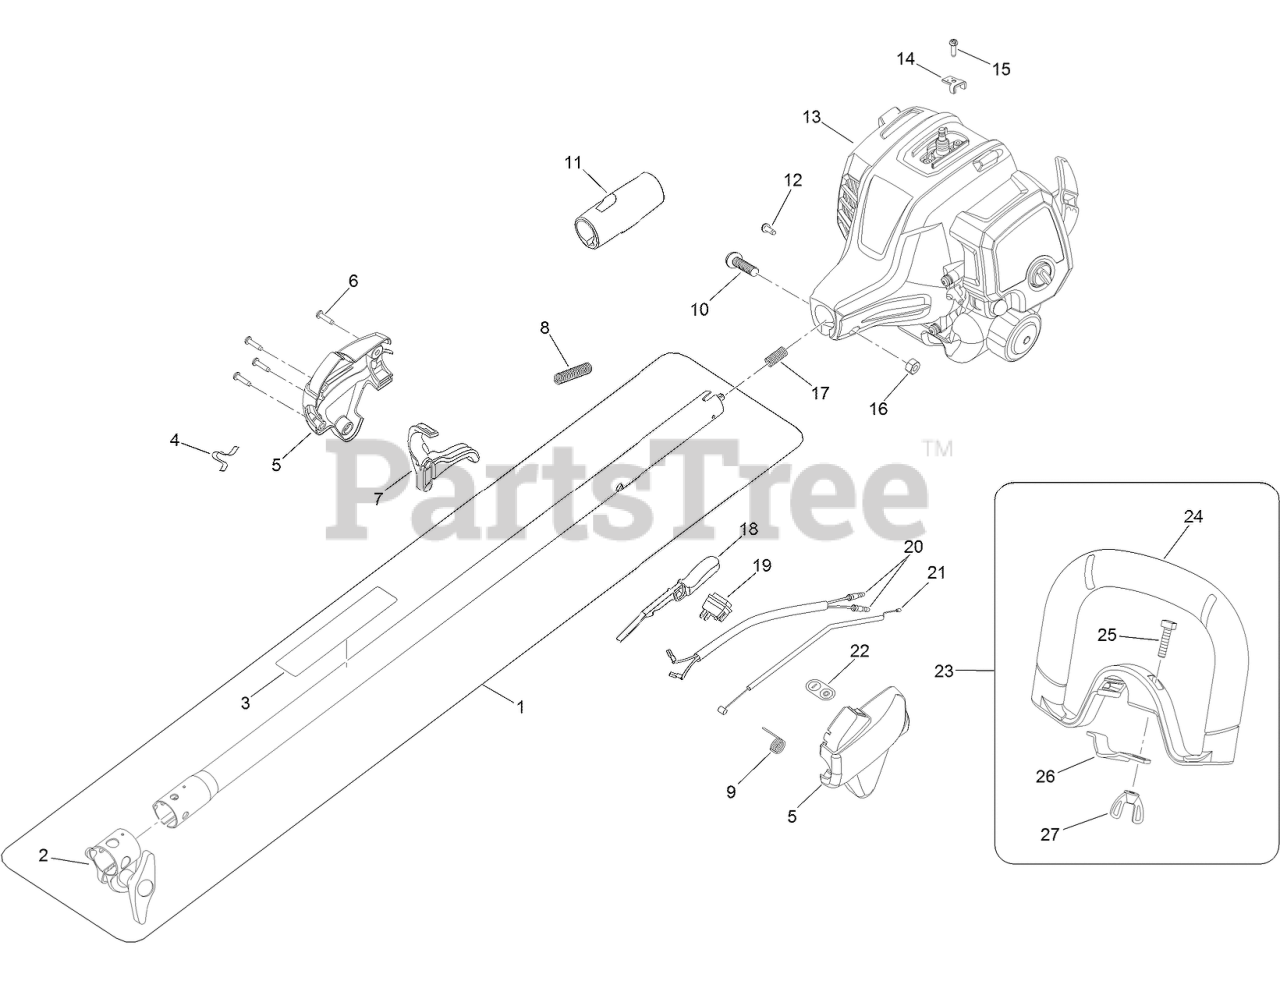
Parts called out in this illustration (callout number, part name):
1	UPPER SHAFT ASM
2	SHAFT CLAMP ASM
3	DECAL-WARNING
4	CLIP-STRAP, SHOULDER
5	CONTROL HANDLE ASM
7	TRIGGER
8	TUBE-CORRUGATED
9	SPRING-TRIGGER
11	GRIP-SHAFT, UPPER
14	CLAMP-CABLE, THROTTLE
16	NUT-HEX
17	SPRING-COMPRESSION
18	LOCK-TRIGGER
19	SWITCH-ON/OFF
21	CABLE-THROTTLE
22	LABEL-ON/STOP
23	HANDLE ASM
24	HANDLE-SHAFT, UPPER
26	CLAMP-HANDLE, UPPER SHAFT
27	NUT-WING
